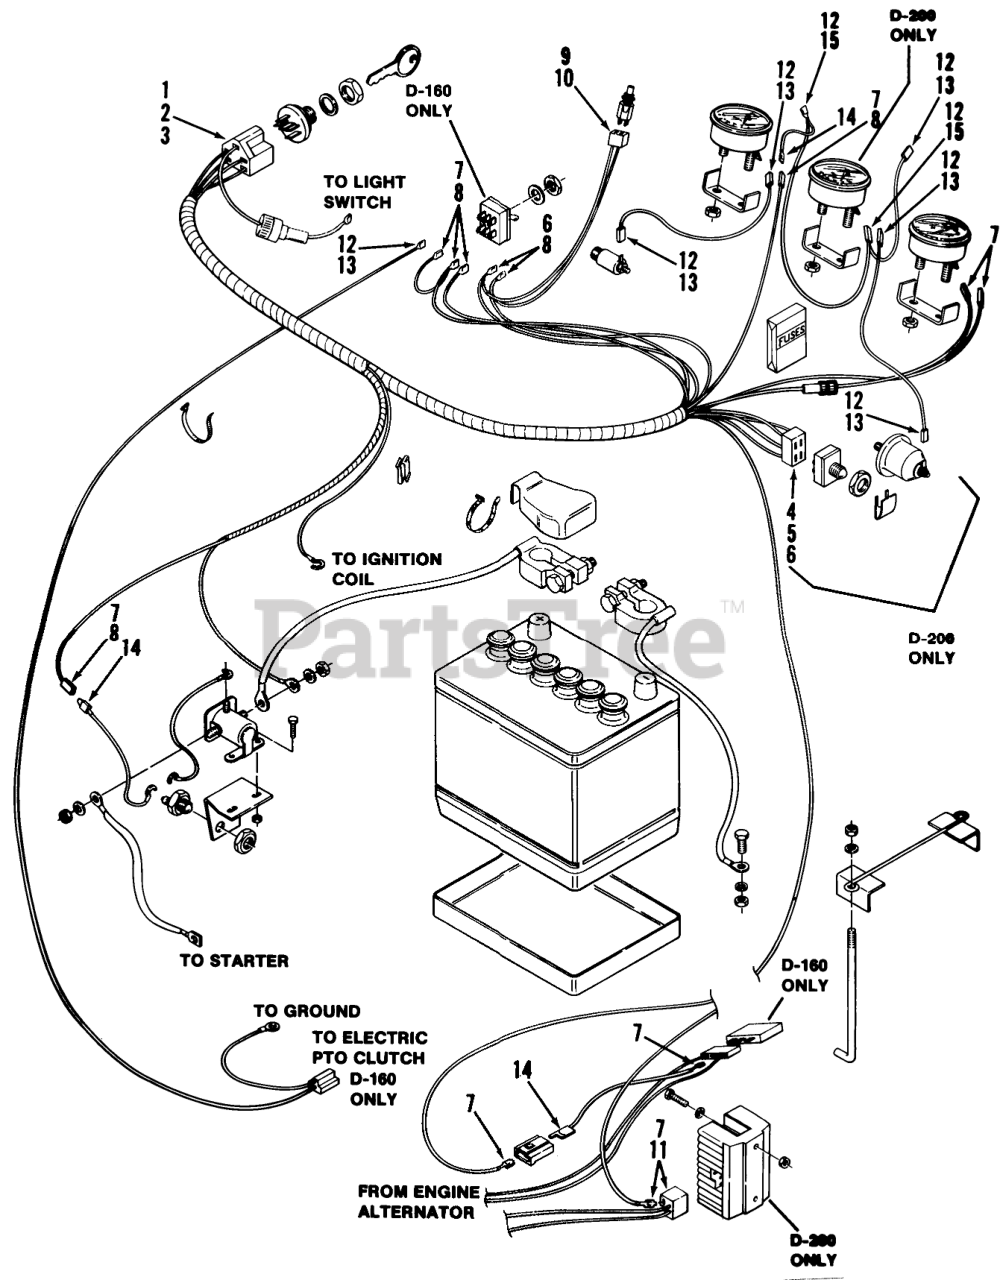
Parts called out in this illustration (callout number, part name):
3	TERMINAL-TAB RCPT
4	CONNECTOR 5 WAY
6	TERMINAL-TAB RCPT
8	CONNECTOR BODY ELECT
9	Connector Body
12	CONNECTOR BODY ELECT
15	TERMINAL-TAB RCPT
